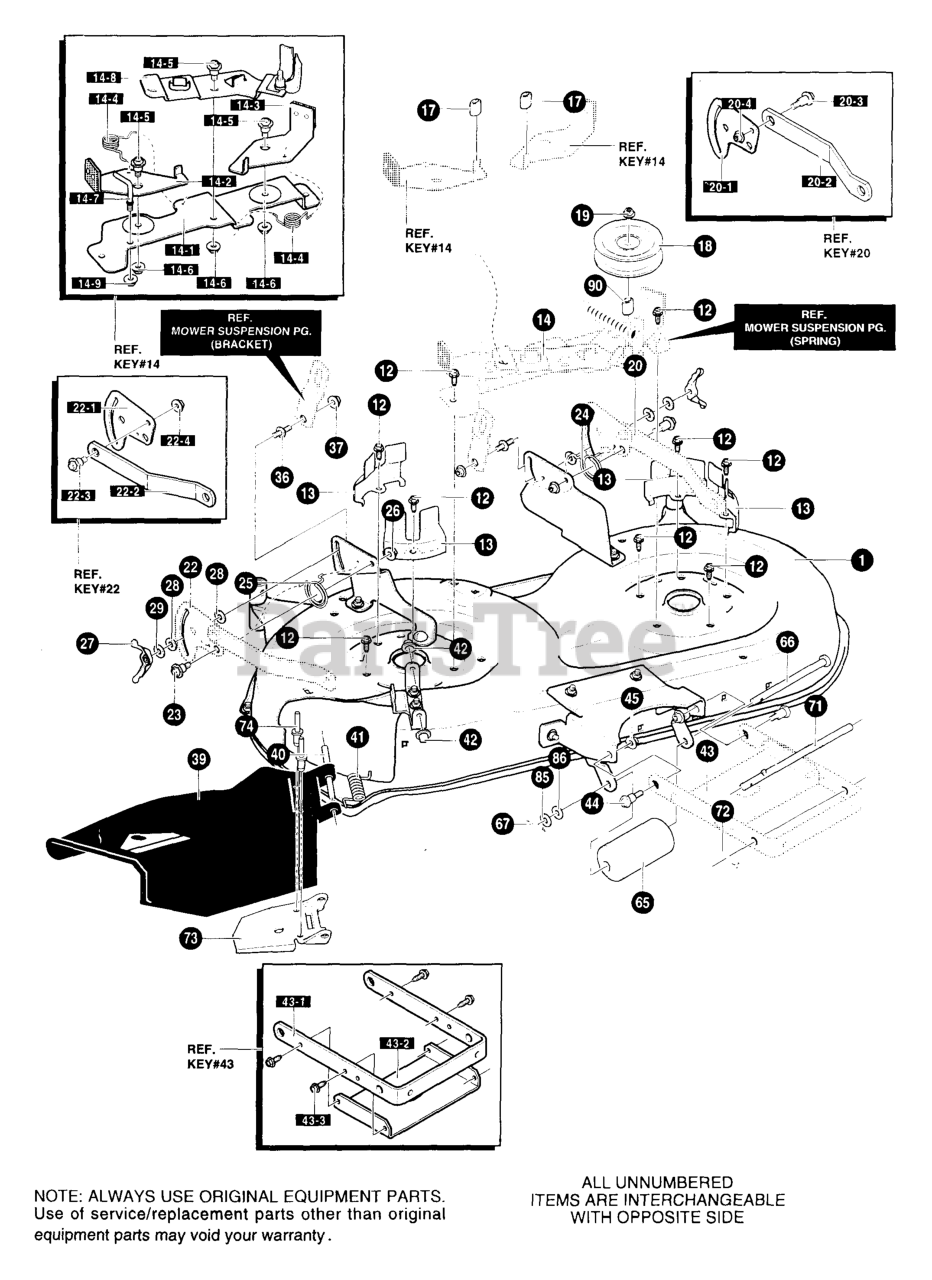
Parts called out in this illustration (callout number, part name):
1	SUB ASSY 42" MOWER DECK DELUXE
12	SCREW, 3/8-16 x 1.25 WAHHSPTAPP
13	COVER, SEGMENT BELT GUIDE
14	ASM., BRACKET SUP W/BRAKES 42"
14-1	BRACKET, BRAKE MT
14-2	ASSY, BRAKE RH
14-3	ASSY, BRAKE LH
14-4	TORSION SPRING (166X41)
14-5	BOLT.50X.75 HHSH 3/8-16 (9X39)
14-6	NUT, 3/8-16 HWDFLLK MACK (15X84)
14-7	SCREW GUIDE
14-8	IDLER ARM ASSY
14-9	NUT, 5/16-18 WDFLLK (15X88)
17	TUBE, BRAKE TAB PAD
18	PULLEY, IDLER
19	NUT,3/8-16HWDFLLK MACK
20	ASM.PLATE,REAR SUS.BRKT.LH
20-1	PLATE - SUSPENSION
20-2	SUSPENSION BRKT REAR
20-3	BOLT, SHOULDER 3/8-16 (9X52)
20-4	NUT,3/8-16HWDFLLK MACK 15X84 Z
22	ASM.PLATE,REAR SUS.BRKT.RH
22-1	PLATE - SUSPENSION
22-2	SUSPENSION BRKT REAR
22-3	BOLT, SHOULDER 3/8-16 (9X52)
22-4	NUT,3/8-16HWDFLLK MACK 15X84 Z
23	BOLT, SHOULDER.375 (9X51)
24	SPRING,TORSION.68LG LH 166X43
25	SPRING,TORSION.68LG RH 166X42
26	NUT,3/8-16HWDFLLK MACK 15X84 Z
27	WING KNOB 5/16-18
28	PAD, FRICTION
29	WASHER, (17X45)
36	PIN, HANGER
37	NUT, 3/8-16 HWDFLLK MACK
39	CHUTE DEFLECTOR
40	ROD, CHUTE DEFLECTOR
41	SPRING, TORSION .44X2.06X
42	NUT, PUSH CAP.375 (28X23) Z
43	ASM.,BRACKET & STIFFNER
43-1	BRACKET, FRONT SUSPENSION
43-2	STIFFNER
43-3	SCREW, 5/16-18 x 0.75
44	BOLT, SHOULDER.375 (9X51)
45	NUT,3/8-16HWDFLLK MACK 15X84 Z
65	ROLLER 6 X.515 I.D.X 2.5 O.D.
66	ROD, SUPPORT ZINC
67	PIN, COTTER.125 DIAX1.00LG Z
71	ZINC ROD HANGER
72	HAIR PIN (31X4)
73	SUPPORT, DEFLECTOR
74	RIVET - SEMI.244X.250 (7X125)
85	FLATWASHER
86	WAVE WASHER.50113
90	SPACER 1/2 TO 17MM
